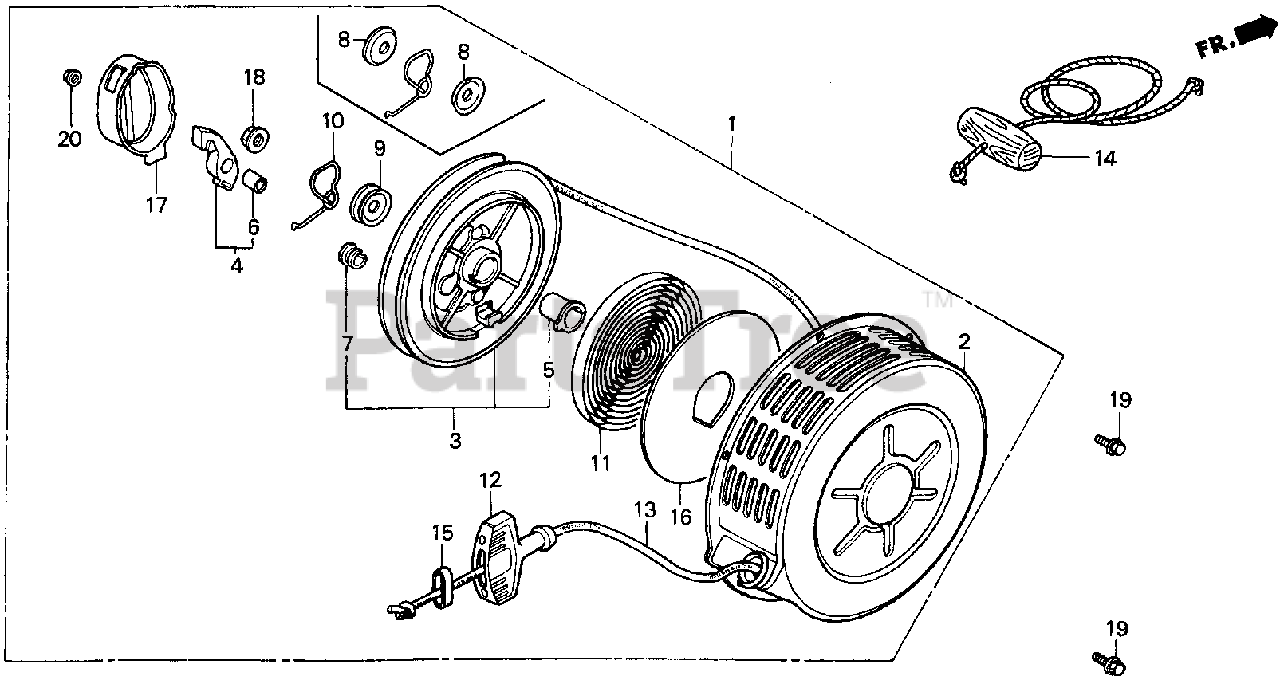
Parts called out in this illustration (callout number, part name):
1	STARTER ASSY., RECOIL *R8* (BRIGHT RED)
2	CASE, STARTER
3	REEL, STARTER
5	BOSS, REEL
6	BUSH, RATCHET
7	BUSH, REEL STARTER
9	PLATE, FRICTION
10	SPRING, FRICTION
11	SPRING, RETURN
12	GRIP, STARTER
13	ROPE, RECOIL STARTER (#5X55")
14	ROPE, STARTER (#5X55")
15	SUPPORT, GRIP
16	PLATE, SIDE
17	COVER, REEL STARTER
18	NUT, SELF-LOCK (8MM)
19	BOLT, FLANGE (6X8)
20	NUT, FLANGE (5MM)
